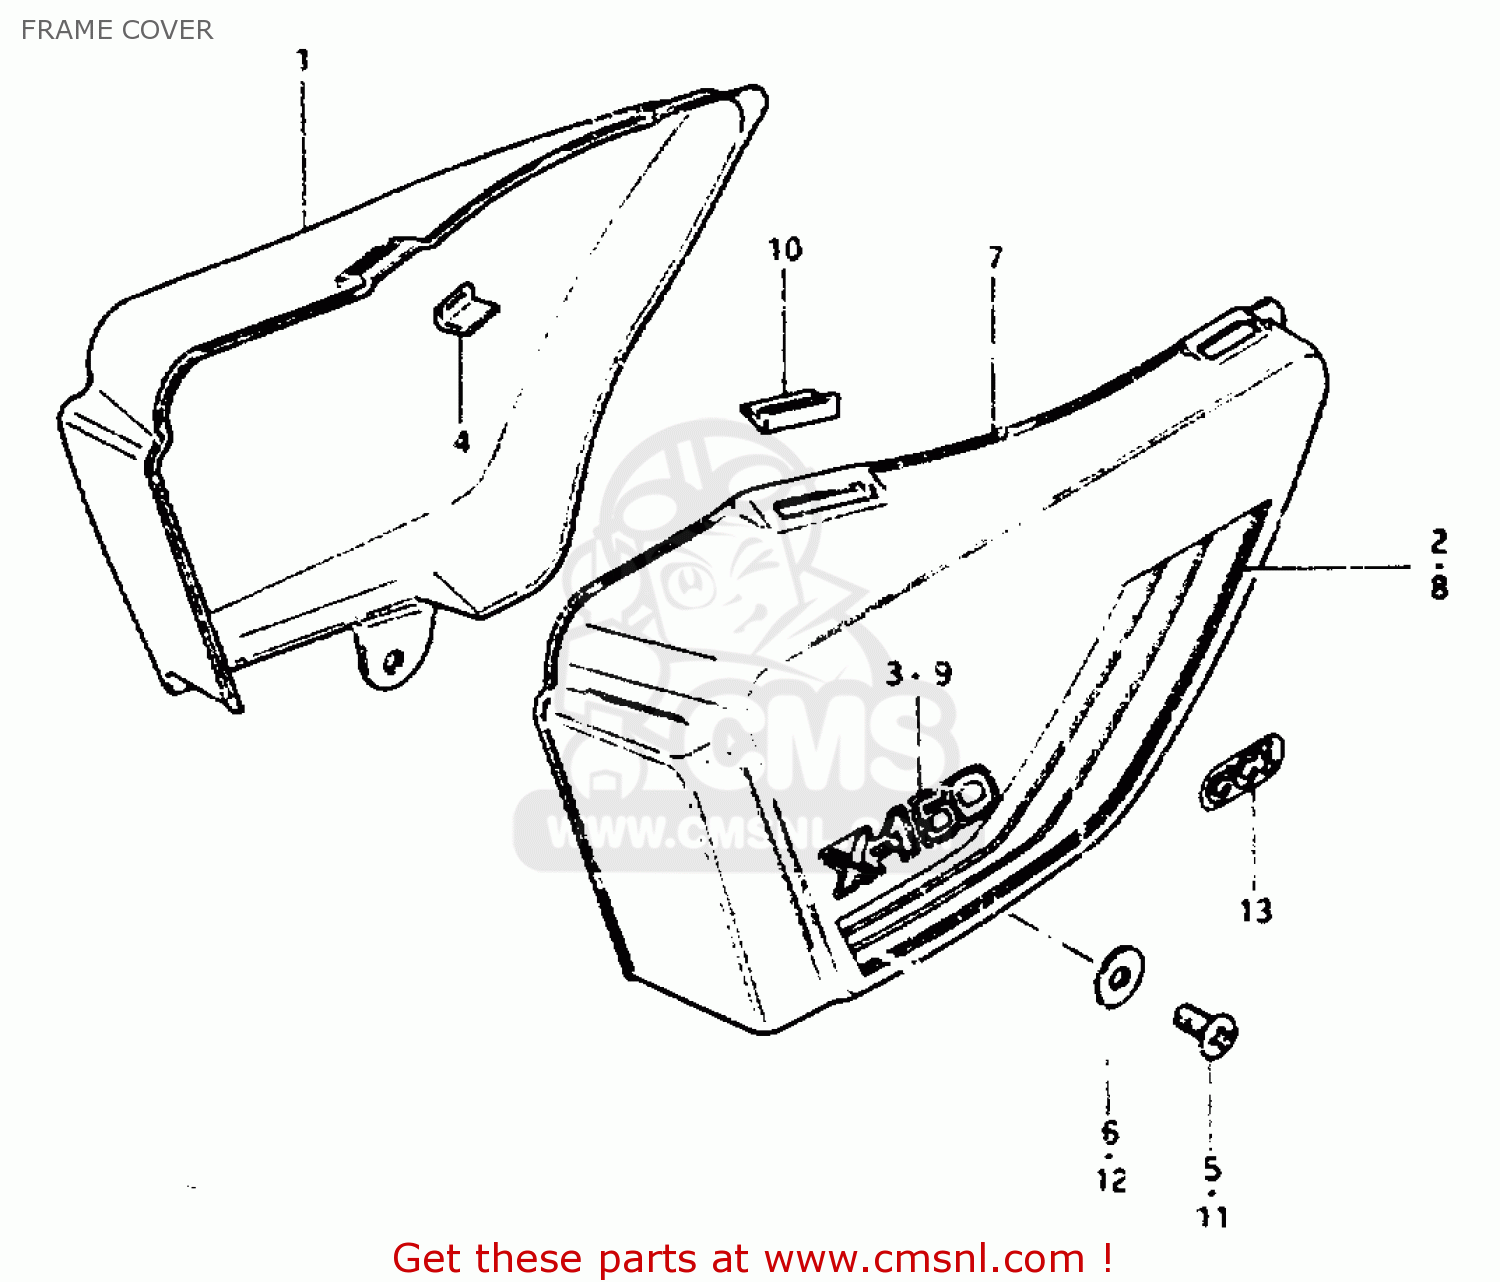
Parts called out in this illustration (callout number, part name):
1	COVER, FRAME RH (BLACK)
2	TAPE, STRIPING RH
3	EMBLEM, LH
4	CUSHION,FRAME COVER
5	SCREW
6	WASHER
7	COVER, FRAME LH (BLACK)
8	TAPE, STRIPING LH
9	EMBLEM, LH
10	CUSHION,FRAME COVER
11	SCREW
12	WASHER
13	EMBLEM,CCIS
